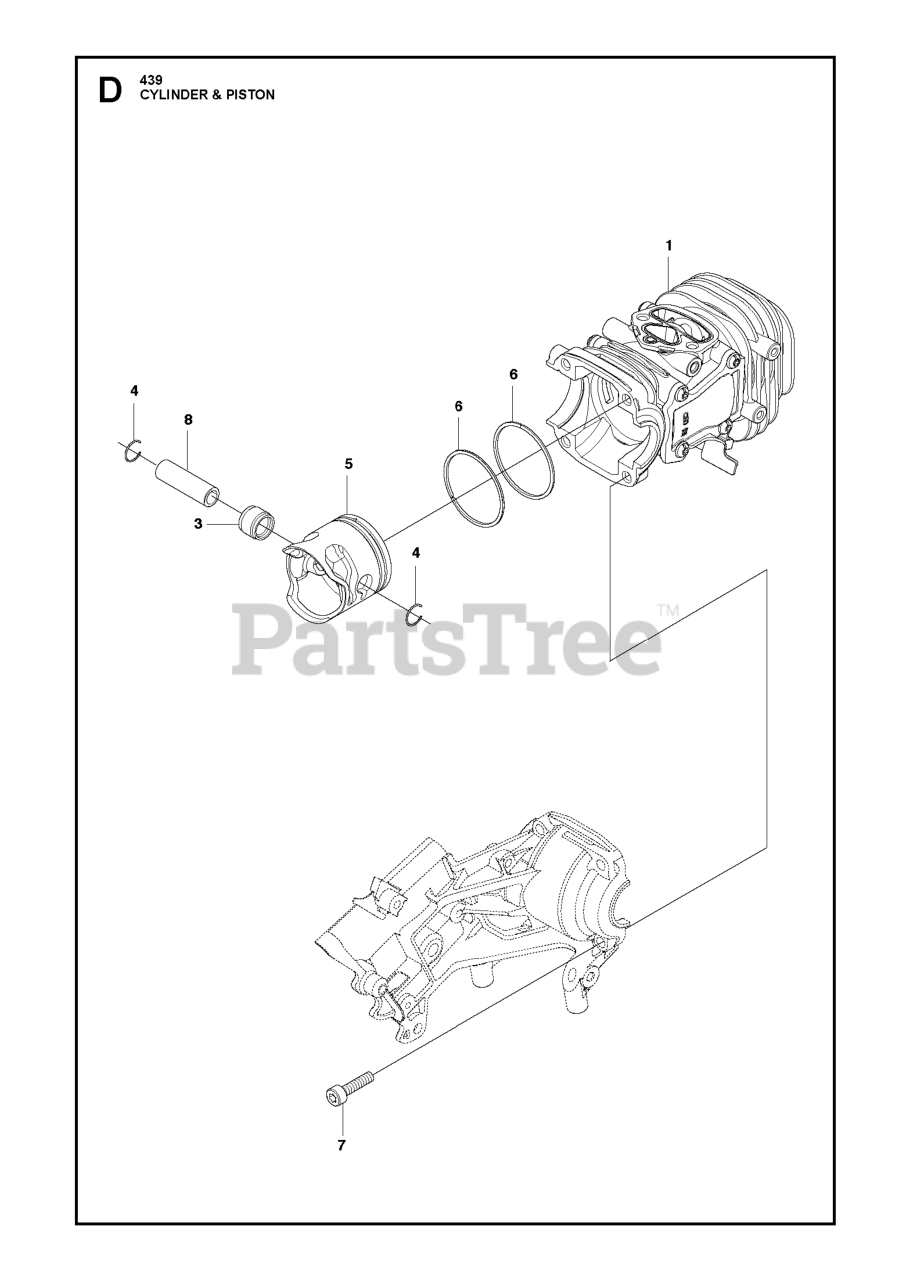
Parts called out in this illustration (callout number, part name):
1	CYLINDER ASSY
3	ROLLER BEARING
7	BOLT
